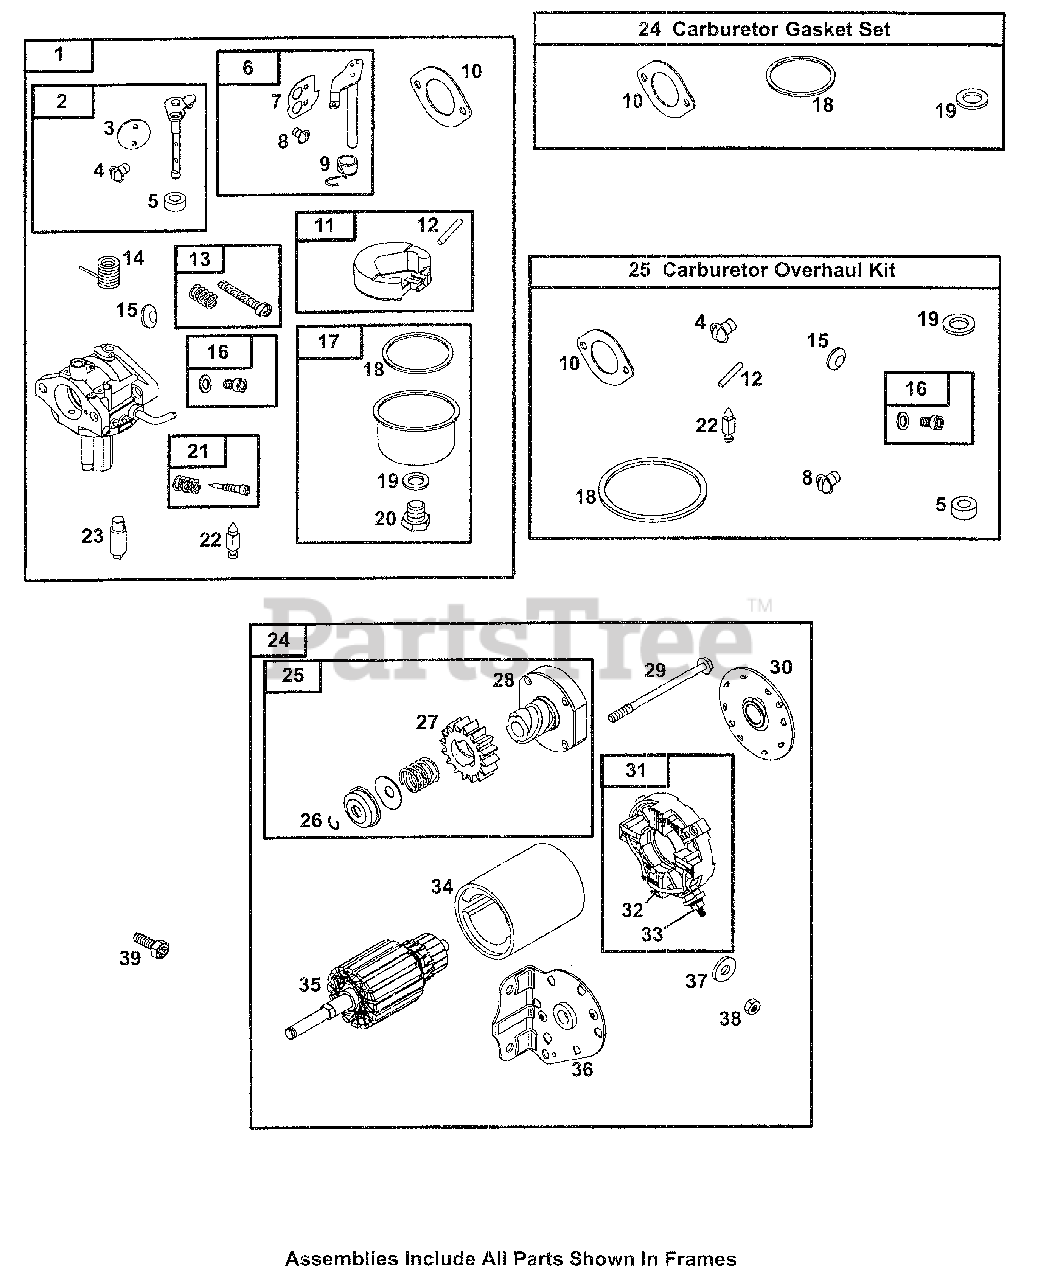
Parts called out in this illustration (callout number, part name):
1	Carb (choke-a-matic and manual choke)
2	Throttle Shaft Kit
3	Throttle Valve
4	Screw (Throttle Valve)
5	Throttle Shaft Seal
6	Choke Shaft Kit
7	Choke Valve
8	Screw (Choke Valve)
9	Choke/Throttle Shaft Seal
10	Intake Gasket
11	Carburetor Float
12	Float Hinge Pin
13	Idle Speed Kit
14	Choke Return Spring
15	Welch Plug
17	Float Bowl
18	Float Bowl Gasket
19	Sealing Washer
20	Float Bowl Screw
21	Idle Mixture Kit
22	Float Needle Valve
23	Fuel Solenoid
24	Starter Motor
25	Starter Drive
26	Retaining Ring
27	Pinion Gear
28	Drive Clutch
29	Bolt (Starter Motor)
31	Brush Retainer
33	Nut (Brush Retainer)
34	Starter Housing
35	Starter Armature
36	Drive Cap
37	Washer (Starter Cable)
38	Nut (Brush Retainer)
39	Screw (Drive Cap)
